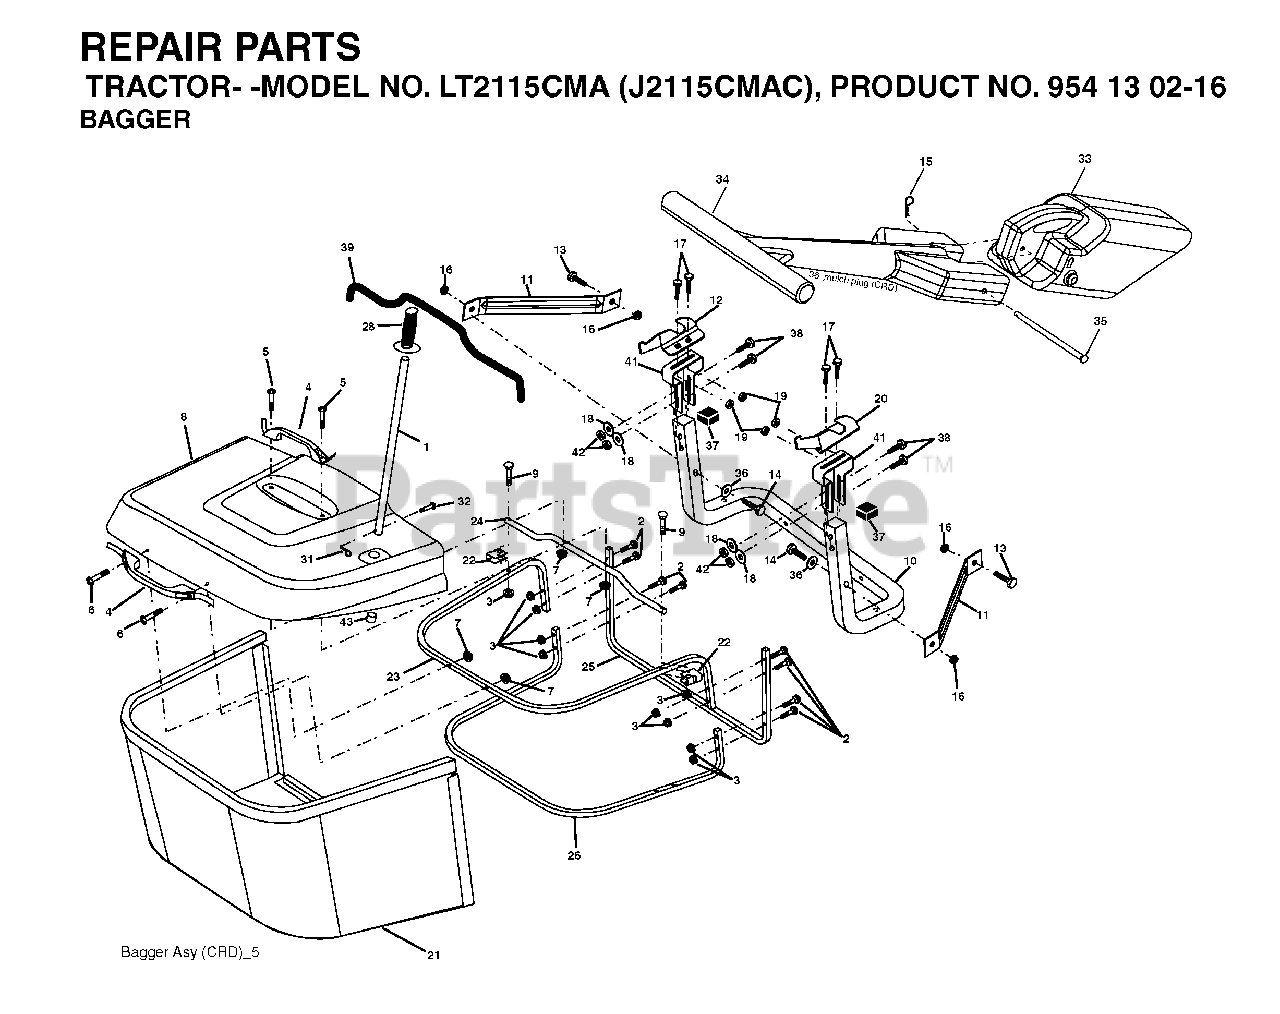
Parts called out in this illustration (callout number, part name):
1	TUBE HANDLE
3	NUT T
5	SCREW.PAN.HEAD
11	BRACKET
14	BOLT-HEX EAK
15	RETAINER-SPRNG RB
16	NUT LOCK FLG 3/8-16 UNC
17	BOLT
18	WASHER M
19	NUT LOCK HEX FLANGE 5/16-18
20	BRACKET
21	GRASS BAG
22	BRACKET
23	TUBE
24	TUBE
26	TUBE
28	GRIP.HANDLE.BLACK
31	RETAINER CLIP
32	RIVET,DRILLED
33	PLUG
35	PIN
36	WASHER
38	BOLT.5/16-18X2.5
41	BRKT, BAGGER
42	NUT.71038.31-18.HEX.NYLOCK
43	PLUG, TUBING END
